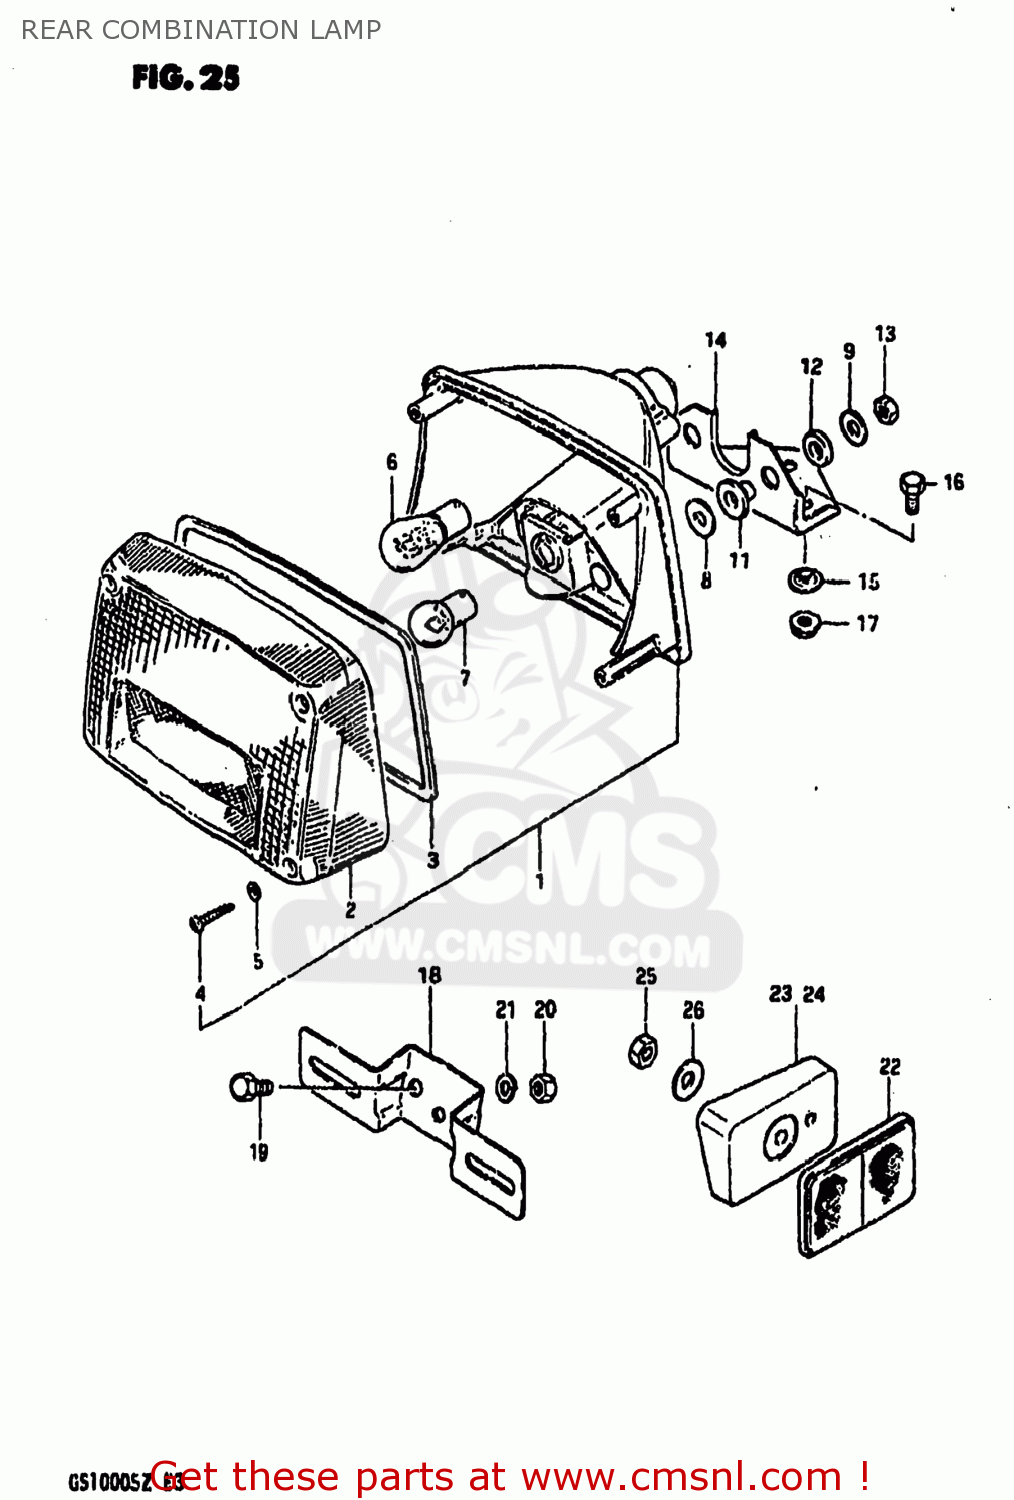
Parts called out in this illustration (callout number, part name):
1	LAMP ASSY,RR COMBINATION
2	LENS
3	GASKET (NAS)
4	SCREW,REAR COMBINATION LAMP
5	GASKET (NAS)
6	BULB(12V23W)
7	BULB
8	WASHER
9	WASHER(6,5X22X1.6)
10	SPACER(6.1X9X7.5)
11	CUSHION
12	CUSHION
13	NUT 6MM
14	BRACKET,REAR COMBINATION LAMP
15	WASHER
16	BOLT, UPPER
17	NUT 6MM
18	BRACKET,LICENSE PLATE
19	BOLT
20	NUT
21	LOCK WASHER
22	REFLEX REFLECTOR,RR
23	SPACER,REAR REFLEX REFLECTOR
24	SPACER,REAR REFLEX REFLECTOR
25	NUT
26	WASHER
